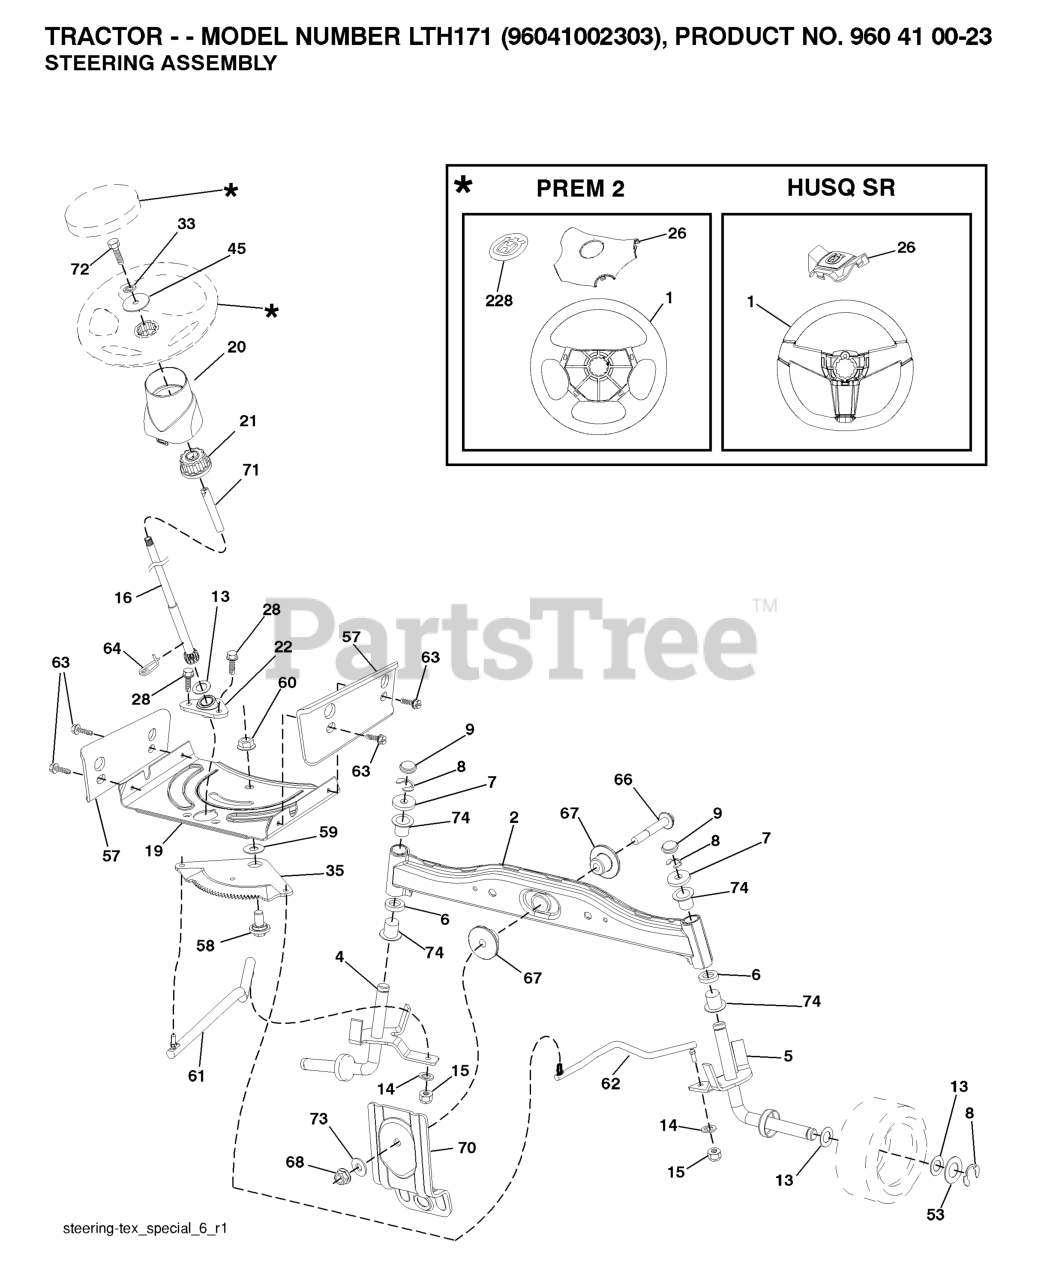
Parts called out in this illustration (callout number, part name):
1	RP WHEEL.STEER.HUSQ.PREM.OVMLD
2	AXLE HALF ASM-WELDED
4	SPINDLE.WELDED.LH.15"TEX
5	SPINDLE.WELDED.RH.15"T
6	THRUST WASHER
9	CAP.SPINDLE.BLACK
14	WASHER, LOCK 3/8
15	NUT CROWNLOCK 3/8-24
16	SHAFT STEERING
19	PLATE.STEER.DDL.NLT/NG
20	BOOT, STEERING
21	ADAPTER, WHEEL STNG..
22	BUSHING.ASM.STEERING.A
26	RP INSERT.CAP.WHL.STRG.HUSQ.
28	SCREW, 3/8-16X3/4
33	WASHER.LOCK.HVY.HLCL.SPR.5/16
35	GEAR.SECTOR.PLATE.DDL.
45	WASHER.11/32
53	WASHER.HARDENED
57	BRACKET.UPSTOP.TEX
58	BOLT.SHOULDER.SECTOR.P
59	WASHER.THURST.SECTOR.S
60	NUT FLANGE LOCK 5/8-11
61	DRAGLINK.LH.BALLSTUD.D
62	DRAGLINK.RH.BALLSTUD.D
63	SCREW
64	RETAINER.CLIP.SPRING.S
66	BOLT HEX FGHD 7/16-14 X 3 SERR
67	BUSHING.PM.FRONT AXLE
68	NUT.LOCK.FLANGE.7/16
70	BRKT.DECK.SUSPENSION.F
71	SHAFT EXTENSION STEERING
72	BOLT YT
73	WASHER.1.5X.505X.118
74	BRNG T
228	DECAL.WHEEL.STRG.LGN.H
